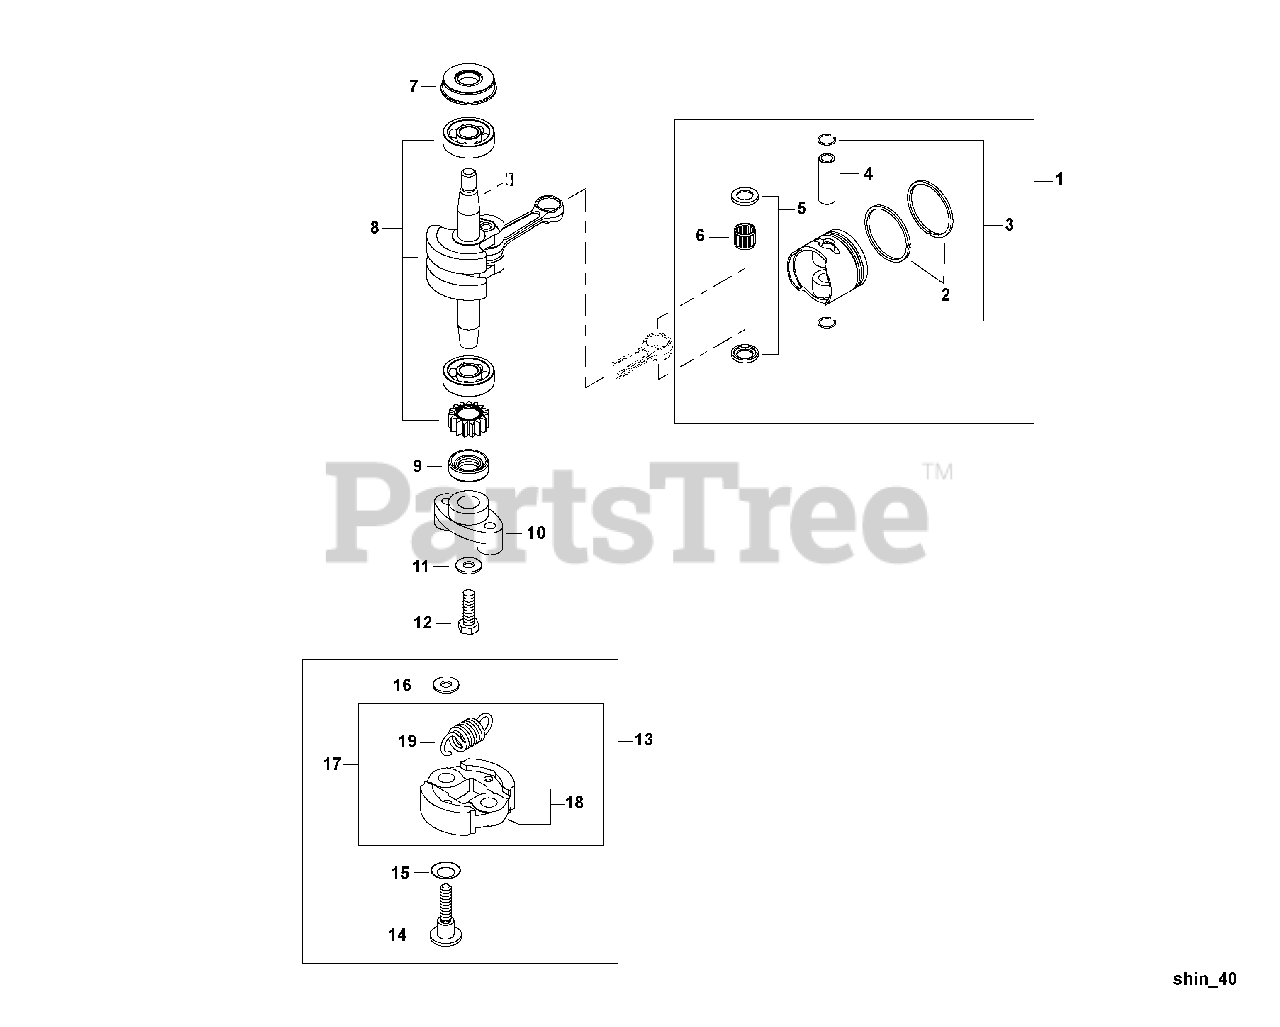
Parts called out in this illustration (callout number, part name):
1	PISTON KIT
2	RING, PISTON
3	RING, SNAP
4	PIN, PISTON
5	WASHER, THRUST 9
6	BEARING, NEEDLE 9
7	SEAL, OIL 12
8	CRANKSHAFT ASSY
9	SEAL, OIL 12
10	BOSS, CLUTCH
11	WASHER 6 MM
12	BOLT M6×18
13	CLUTCH KIT
14	BOLT, CLUTCH
15	WASHER, SPRING
16	WASHER 6 MM
17	SHOE ASSY, CLUTCH
18	SHOE, CLUTCH
19	SPRING, CLUTCH
